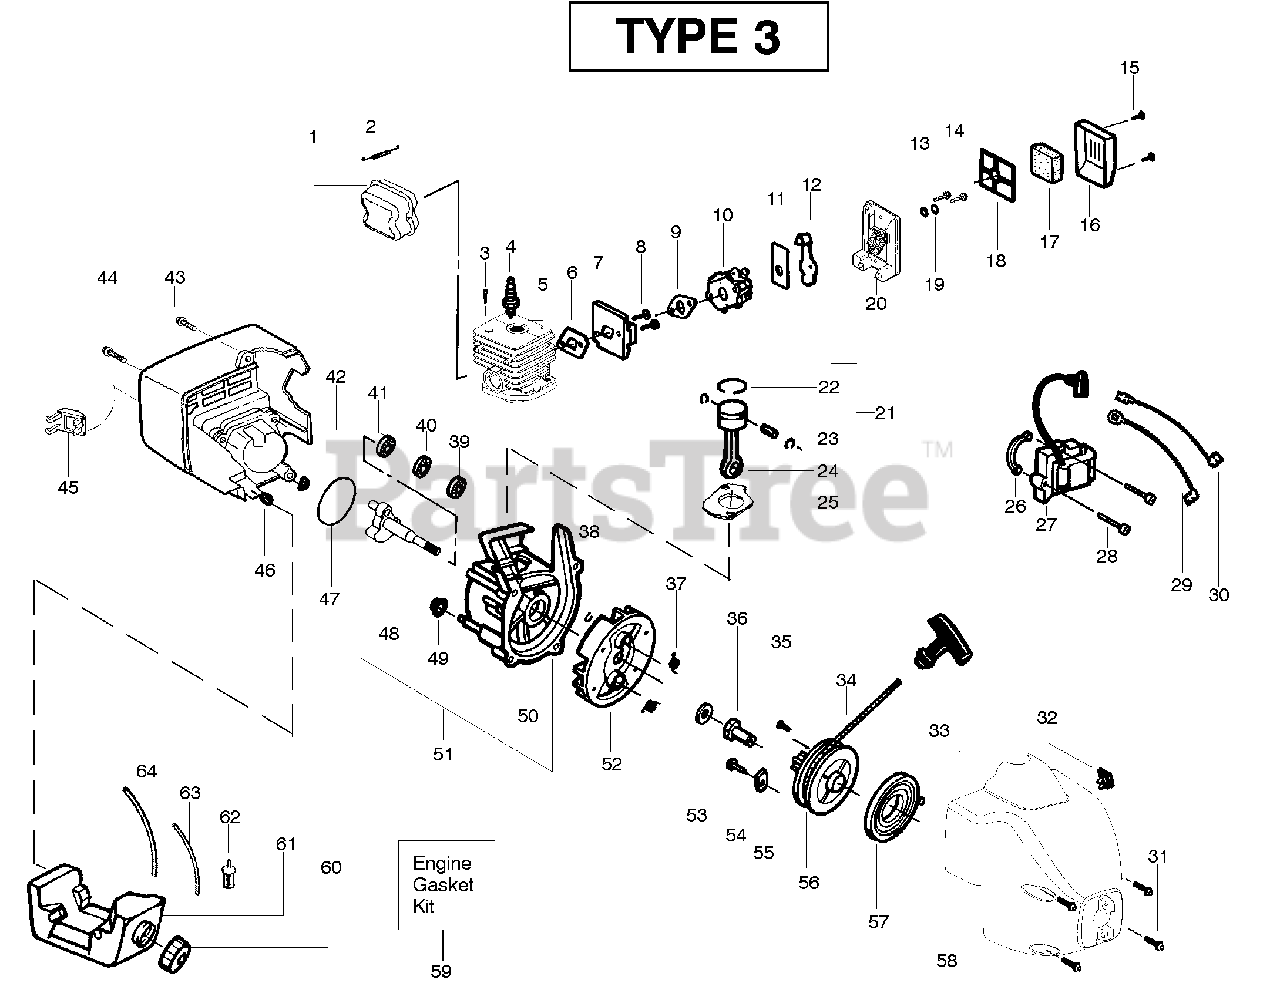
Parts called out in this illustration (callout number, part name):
1	Kit - Muffler
2	Muffler Spring
3	Screw-Cylinder
4	Spark Plug (RCJ 6Y)
5	Kit - Cylinder
6	Gasket-Cyl/Carb.(kit)
7	Adaptor-carb.
9	Gasket-Carb.(kit)
10	Kit-Carb. (WA226)
11	Plate-Choke Mounting
12	Lever-Choke
16	Cover-Air Box
17	Foam-Air Filter
18	Plate-Air Filter Support
19	Spacer-Choke
21	Kit - Piston
22	Piston Ring
23	Retainer-Piston Pin
24	Assy-Connecting Rod
25	Gasket-Cylinder(kit)
26	Spacer-Module
27	Ignition Module
29	Assy-Ground Wire
30	Assy-Leadwire
31	Screw
32	Kit-Switch
33	Handle-Starter
34	Kit - Rope
36	Coupling-Drive
37	Spring-Starter Dog
38	Retain. Ring-C'shaft
39	Bearing-Outer
40	Kit-Seal C'case
41	Bearing-Inner
44	Screw
45	Guard-Muffler
46	Isolator-Shroud
47	O-Ring-C'case(kit)
48	Assy-Crankshaft
49	Isolator-Crankcase
50	Assy-Crankcase
51	Assy-C'case & C'shaft
52	Assy-Flywheel
53	Washer-Flat
55	Retainer-Can
56	Kit-Starter Pulley
57	Spring-Starter
58	Assy-Fan Housing
59	Kit-Engine Gasket
60	Assy-Fuel Cap
61	Assy-Fuel Tank
62	Assy-Fuel Pickup
63	Kit-Fuel Line
64	Kit-Fuel Line
